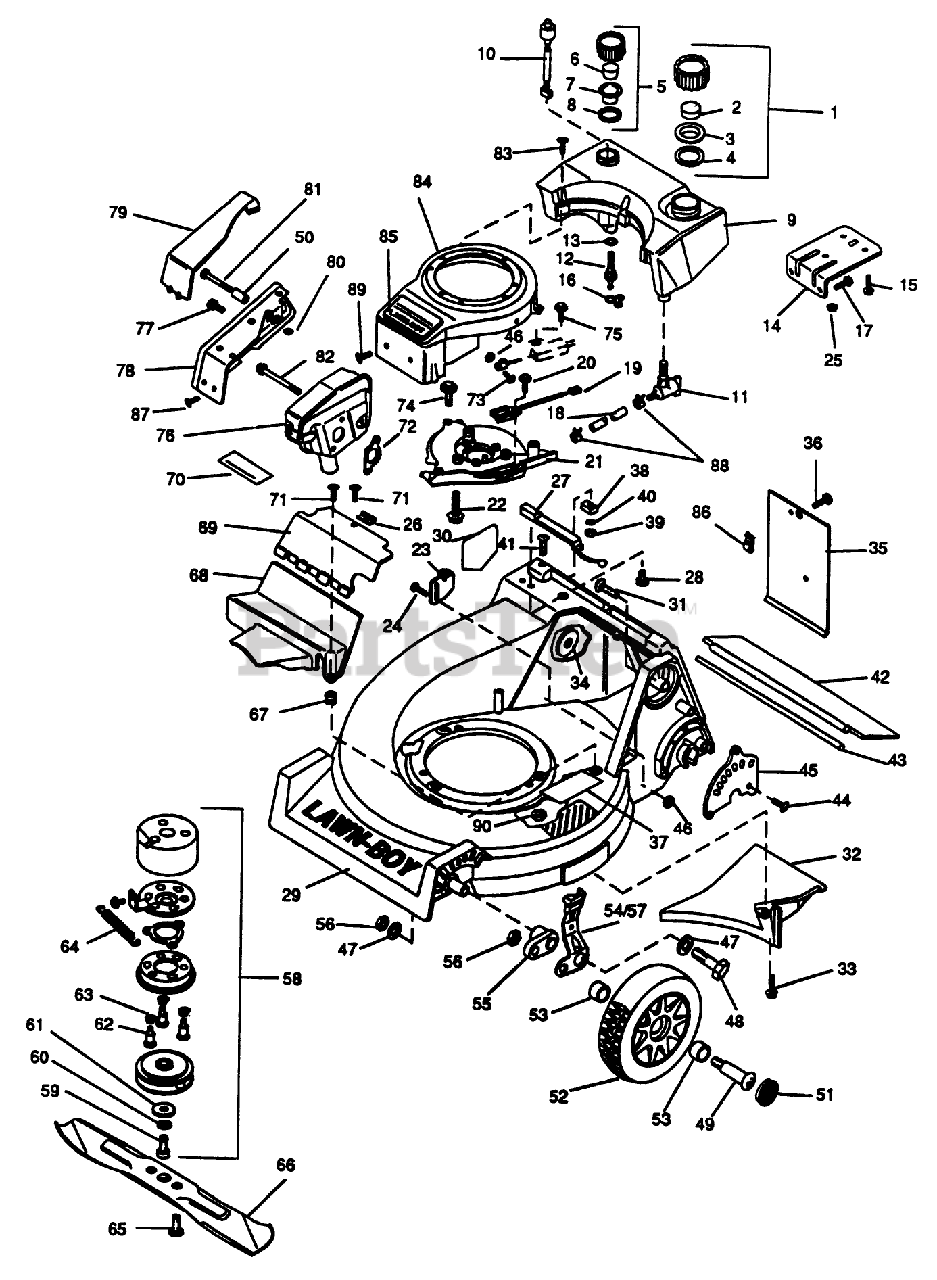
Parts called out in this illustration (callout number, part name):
1	CAP AY - FUEL M
2	BAFFLE - FOAM SM
3	COVER-FUEL CAP F
4	GASKET-FUELCAP SM
5	CAP AY. OIL M
10	SWITCH AY-OIL S
11	DISC/LB SER.BUL.#6
13	O-RING SM
14	DISC. LB SER.BUL.#6
15	DISC/LB SER.BUL.#6
18	GAS LINE SM
22	SCREW-SEMS F
23	ANCHOR-CABLE
26	NUT-SPEED
29	HOUSING ASM.
32	CHUTE BAFFLE NYL
35	DOOR-ACCESS ELECT.
36	SCREW-CROSS RECESS
44	SCREW-BHTF
46	LOCKNUT E
47	WASHER-PLAIN
49	SHOULDER BOLT
50	SPACER S
51	CAP-HUB
53	Bushing-Wheel
54	KNOB & SPRING CMS
55	ARM HGT ADJ *BLACK
56	NUT-JAM, LOCKING
57	KNOB & SPRING CMS
61	WASHER
62	SCREW,SHOULDER SM
64	SPRING
65	SCREW SEMS
66	21" Blade
67	NUT-CLIP
72	GASKET - EXH SM
74	SCREW
75	SCREW-HH
77	SCREW S
78	MUFFLER GUARD AY
79	COVER MUFFLER CP
80	NUT-PUSH
81	SCREW SM
82	SCREW-SEMS
83	DISC.LB SER.BUL.#6
85	APPLIQUE SM
86	SPEED NUT LARSON
87	SCREW SM
88	HOSE CLAMP SM
90	NUT-LOCK F
